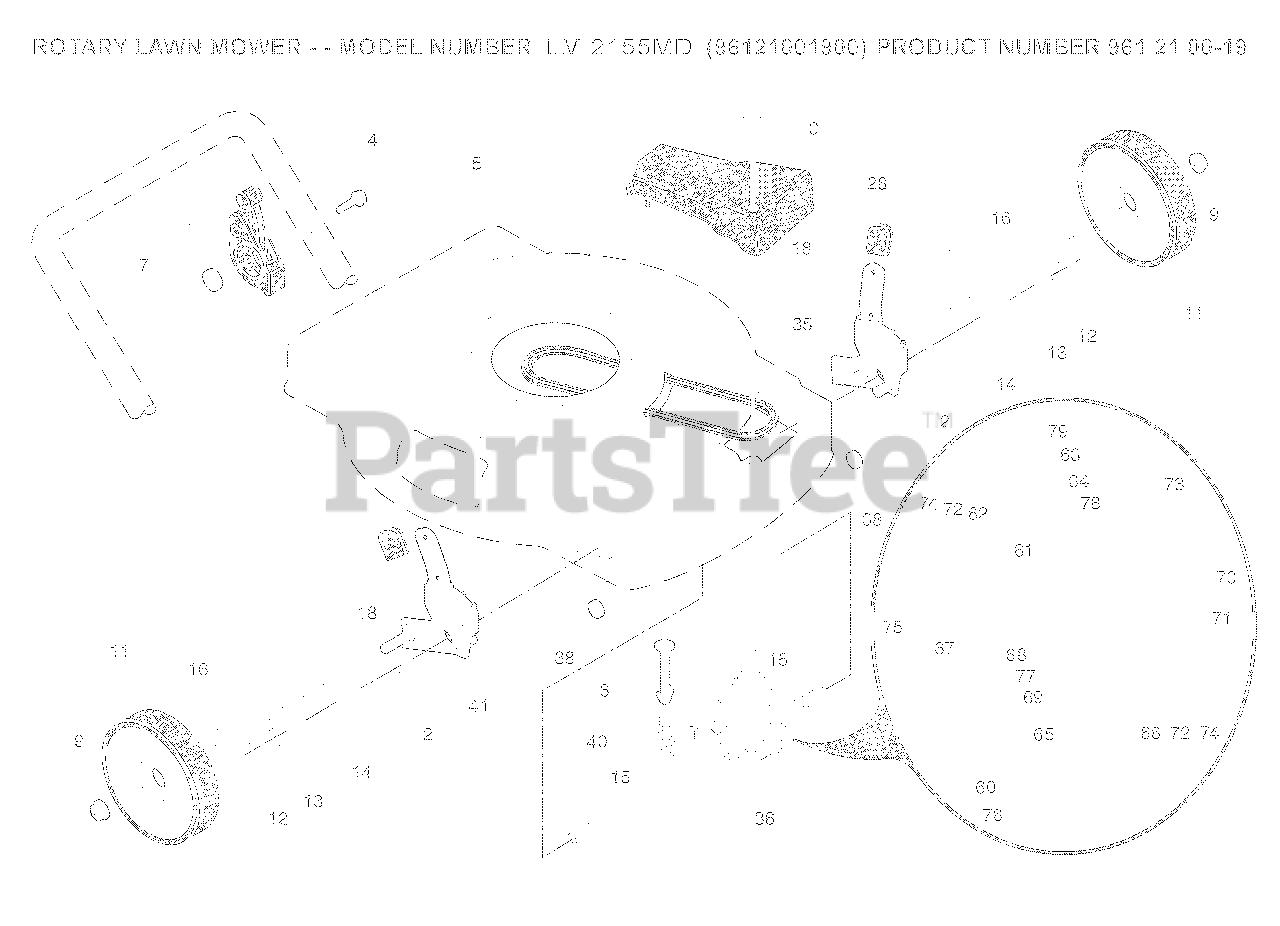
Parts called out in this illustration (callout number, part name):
1	DRIVE CONTROL 59.8 FWGD
2	BEARING ASM
5	BELT THERM .32
6	SPRING RETAINER
7	NUT.HEX.FLANGE.1/4
9	NUT.HEX.FLANGE.3/8-16.LOCKNUT
12	E-RING 7/16 RE
13	PINION.14.TEETH.FGD
14	COVER.DUST.WHEEL
15	PAWL, DRIVE
16	WASHER FLUT
18	SELECTOR KNOB
35	WHEEL ADJ KIT LH
36	TRANSMISSION.22.FGD/W/PULLEY
38	LOCKNUT
40	SPRING.EXTENSION
41	WHEEL ADJ KIT RH
60	LOWER CASE
61	UPPER CASE
62	GEAR.27.TEETH.WALK.MOWER
63	LEVER, CLUTCH
64	SPRING, RETURN
65	SHAFT.INPUT.WORM.GEAR(13155)
66	DOG, MOVABLE
67	DOG, FIXED
68	WIRE, FORMED
70	FORK, SHIFT
71	SEAL.OUTPUT.SHAFT
73	SEAL, CASE
75	SHAFT OUTPUT
77	SEAL INPUT SHAFT
78	FLASK.PULLEY
79	NUT.WITH.FLAT.BROKE
